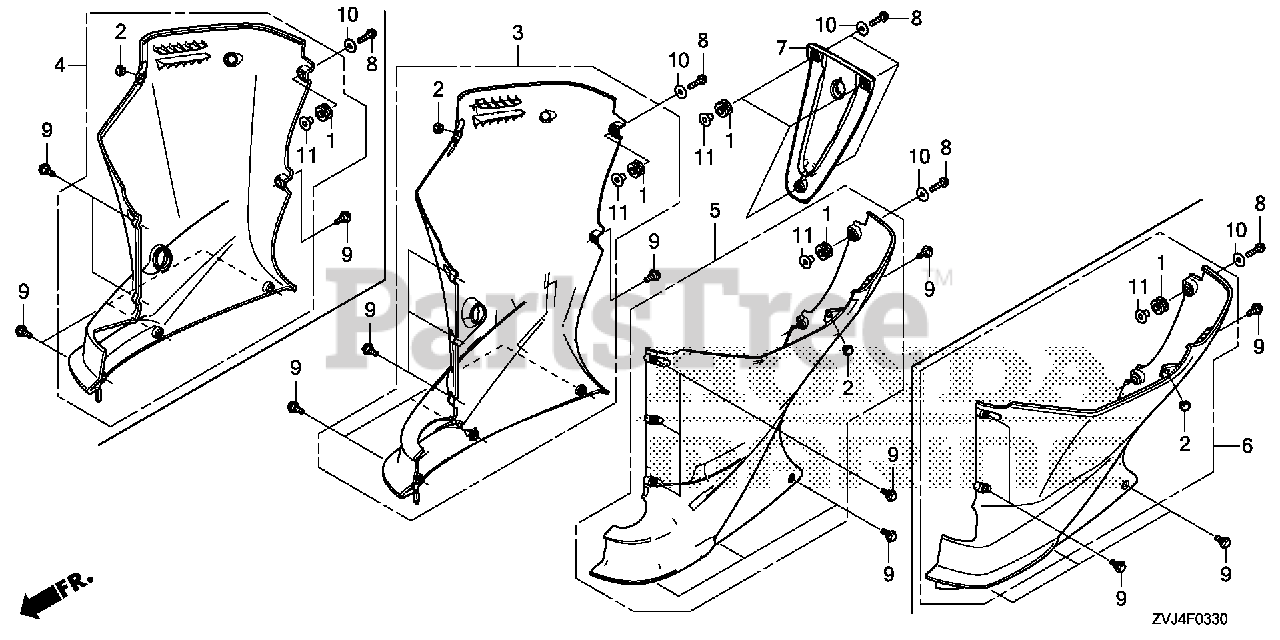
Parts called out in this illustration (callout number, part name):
1	GROMMET, CASE (LOWER)
2	RUBBER, STOPPER
3	COVER, R. ENGINE (LOWER) *NH565* (XL) (GRAND PRIX WHITE)
3	COVER, R. ENGINE (LOWER) *NHB14M* (XL) (AQUA MARINE SILVER METALLIC)
5	COVER, L. ENGINE (LOWER) *NH565* (XL) (GRAND PRIX WHITE)
5	COVER, L. ENGINE (LOWER) *NHB14M* (XL) (AQUA MARINE SILVER METALLIC)
7	COVER, RR.
8	BOLT, FLANGE (6X25)
9	BOLT, SPECIAL (6X17)
10	WASHER, PLAIN (6MM)
11	COLLAR (12X6.5)
